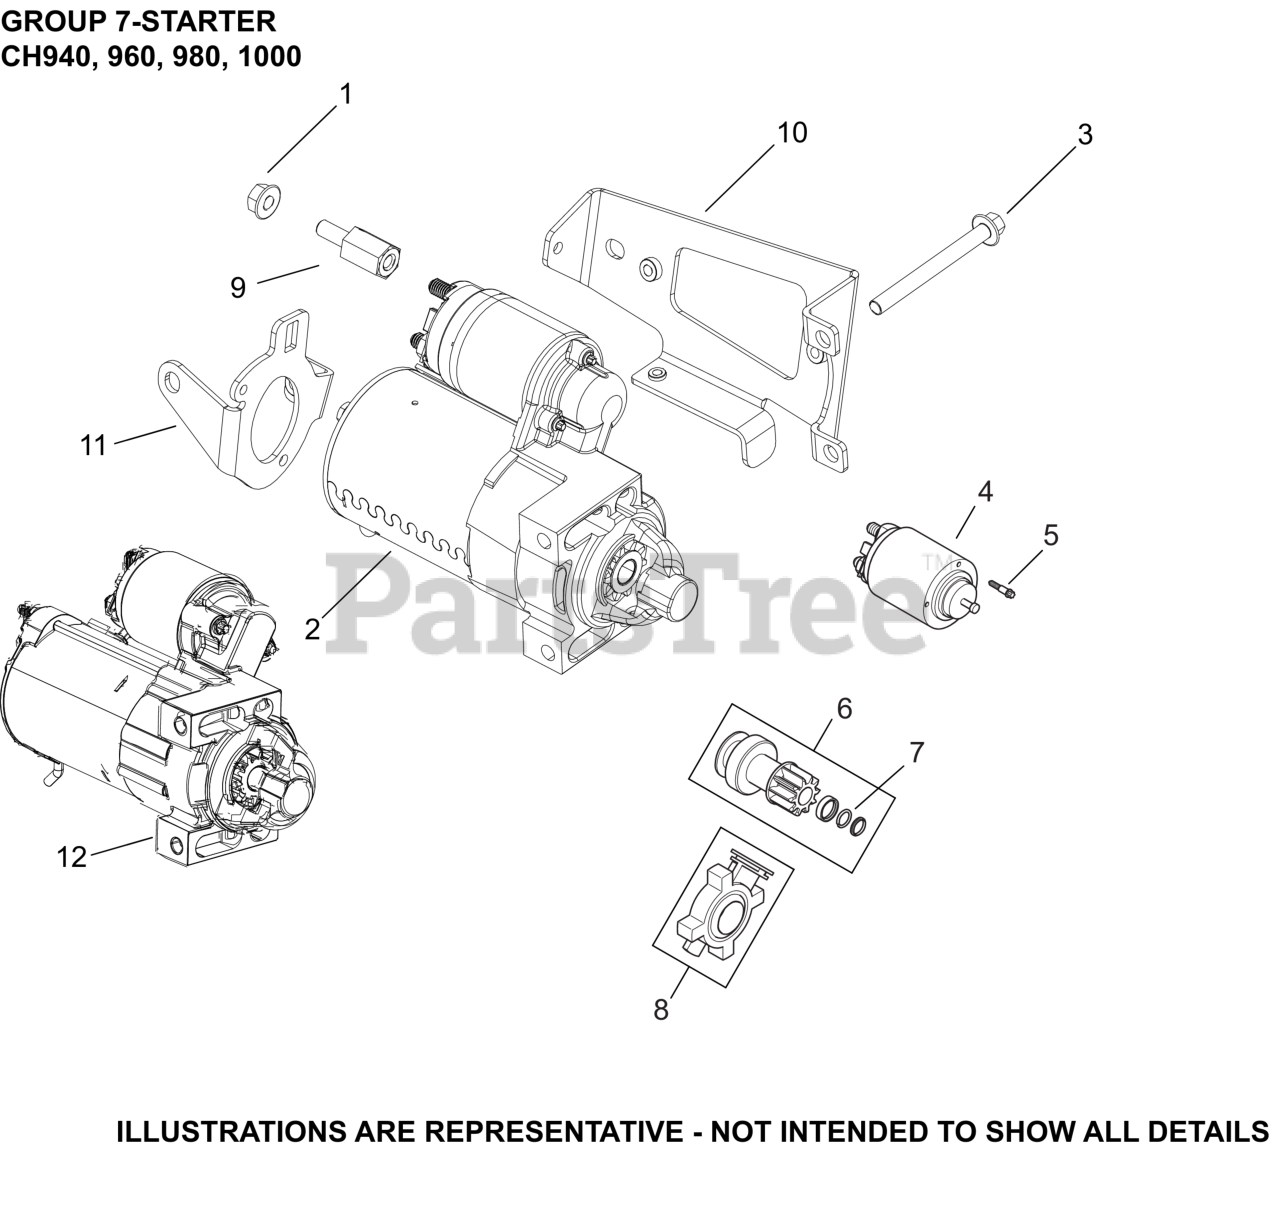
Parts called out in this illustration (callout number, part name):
1	NUT, FLG M8X1.25
3	SCREW, FLG M8X1.25X80
NI	STARTER, SOLENOID SHIFT
